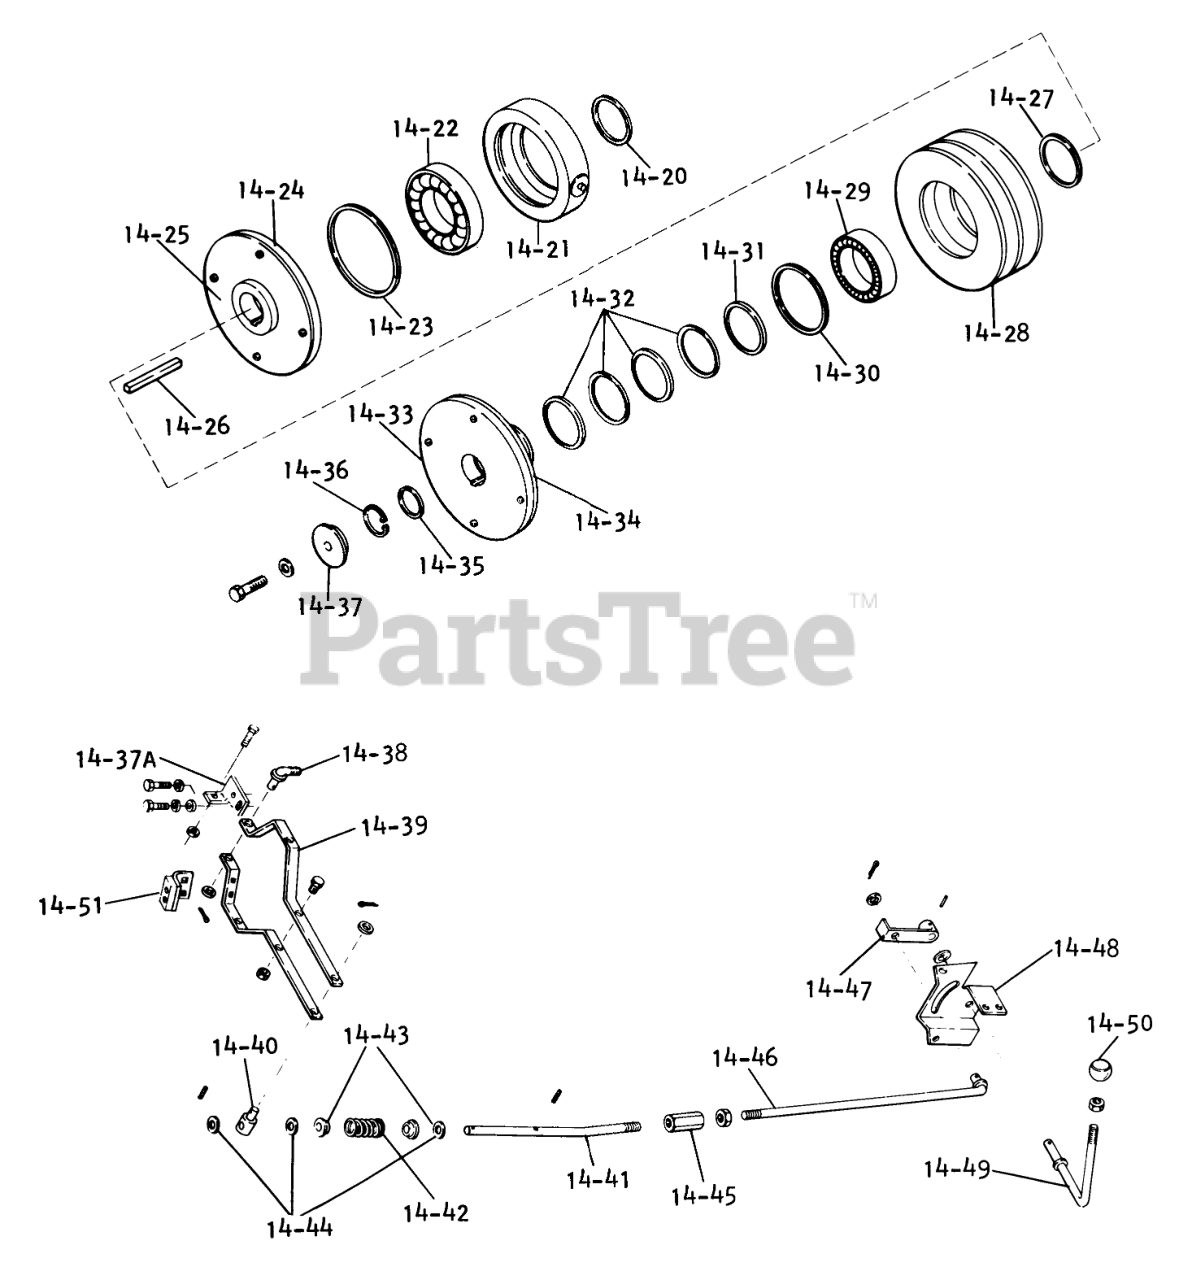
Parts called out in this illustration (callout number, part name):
14-20	RING EXTERNAL
14-21	ASSY COLLAR
14-22	BEARING
14-23	RING INTERNAL
14-24	ASSY CLUTCH PLATE
14-25	CLUTCH FACING
14-26	Key-1/4 x 1/4 x 3, D-160
14-27	RING EXTERNAL
14-28	PULLEY CLUTCH
14-29	BEARING
14-30	RING INTERNAL
14-31	WASHER
14-32	SPRING WASHER
14-33	Assy-Outer Clutch
14-34	CLUTCH FACING
14-35	WASHER
14-36	INTERNAL RING
14-37	END CAP
14-37A	Clutch Bar Bracket, D-160
14-38	ASSY HOOK
14-39	Washer 1/2
14-40	TRUNION
14-41	CLUTCH ROD
14-42	SPRING
14-43	Bushing
14-44	Washer
14-45	TURN BUCKLE NUT
14-46	Assy-Clutch Rod
14-47	ARM CLUTCH ENGAGE
14-48	BRACKET
14-49	ASSY CLUTCH HANDLE
14-51	Clutch Brake
14-52	SWITCH-CLUTCH
14-53	Bracket-Brake
